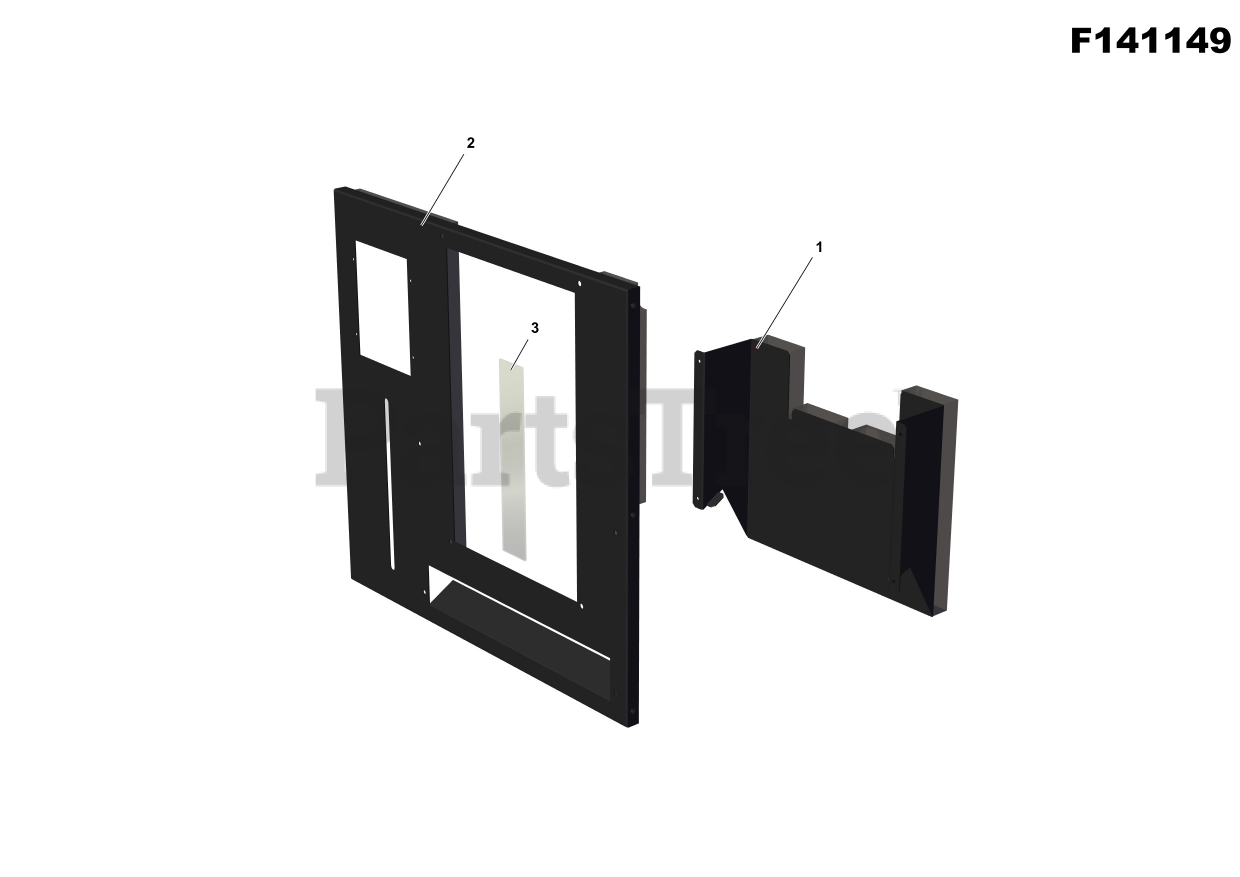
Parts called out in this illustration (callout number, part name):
1	DEFLECTOR
2	REAR PANEL
3	SIGHT GAUGE
